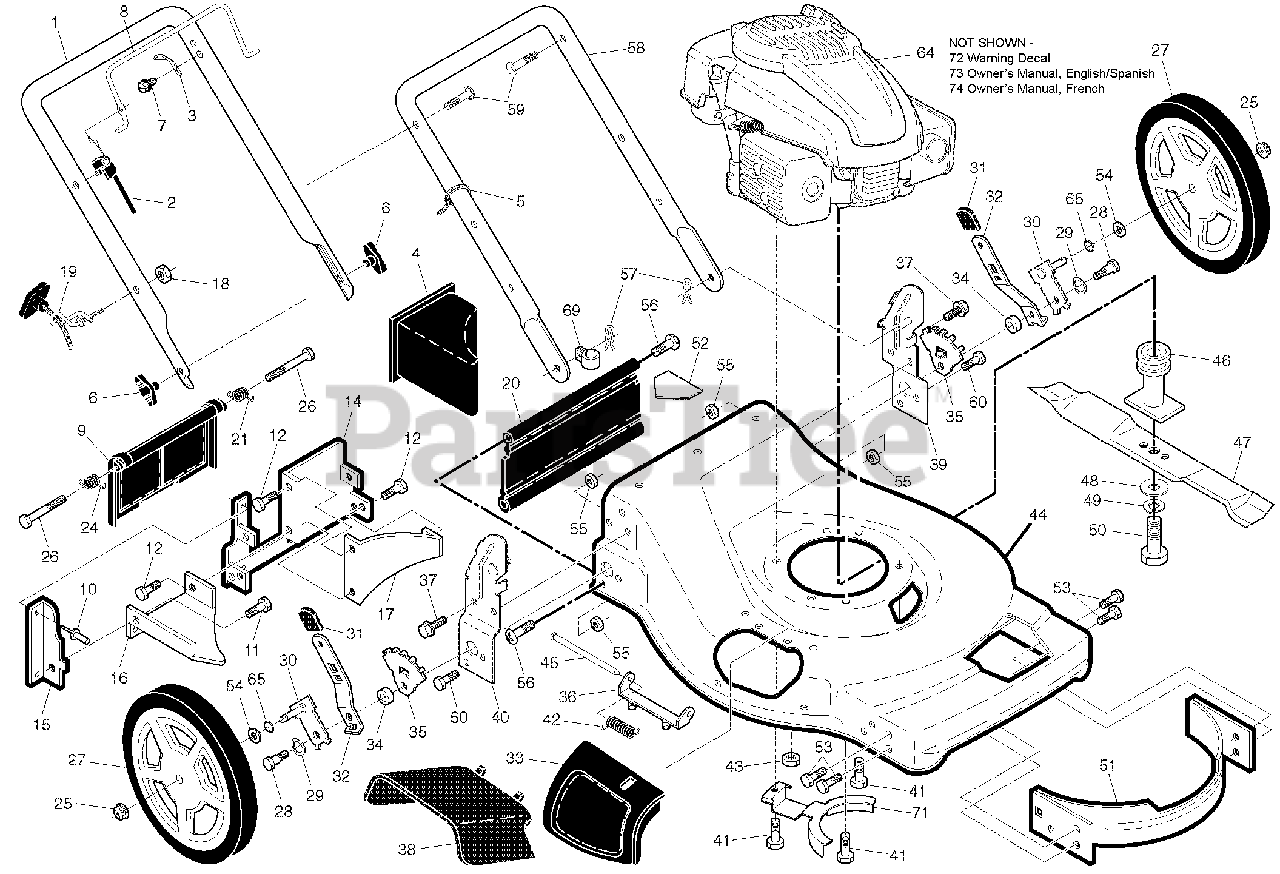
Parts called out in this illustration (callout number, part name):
1	Upper Handle
2	ENGINE CONTROL ZONE CABLE
3	Bracket, Upstop
4	MULCH PLUG
5	Wire Tie
6	Handle Knob
7	Hex Washer Head Screw
8	CONTROL BAR
9	Rear Door Assembly
10	Pop Rivet
11	Screw, Self-Tapping
12	SCREW, SEMS, HEX HEAD 1/4-20 X
14	Back Plate
15	Side Baffle
16	Discharge Baffle
17	Rear Baffle
18	Nut, Hex
19	Rope Guide
20	REAR SKIRT
21	Spring, Rear Door, LH
24	Spring, Rear Door, RH
25	Flanged Locknut, Hex
26	Bolt, Rear Door
27	Wheel & Tire Assy., Rear
28	Bolt, Shoulder 3/8-16 x 1
29	Washer, Curved, Cylindrical
30	Axle Arm Assembly
31	Selector Knob
32	Selector Spring
33	Mulcher Door
35	Wheel Adjusting Bracket
36	Hinge Bracket Assembly
37	Screw, Sems, Thread Cutting 5/
38	Discharge Def ector
39	Handle Bracket Assy., LH
40	Handle Bracket Assy., RH
41	Screw, Hex Head, Threaded, Rol
42	Spring, Torsion
43	Locknut, Hex 1/4-20
44	Kit, Housing
45	Rod, Hinge
46	PULLEY, BLADE ADAPTER
48	Hardened Washer
49	Helical Lockwasher
50	Screw, Hex Head, Grade 8 3/8-2
51	Kit, Front Baffle
52	Danger Decal
53	SCREW.HEX.WASHEAD.1/4-20 X 3/8
54	Washer, Flat
55	NUT.CENTERLOCK.3/8-16 UNC.
56	Hinge Screw
57	Hairpin Cotter
58	Lower Handle
59	Handle Bolt
60	Bolt, Hex Head 3/8-16 x 3/4
64	Engine, Kohler, Model Number XT173-0224-EA (For engine service and replacement parts,
68	WHEEL ADJUSTING BRKT LH
69	Clip, Cable
71	BELT KEEPER
